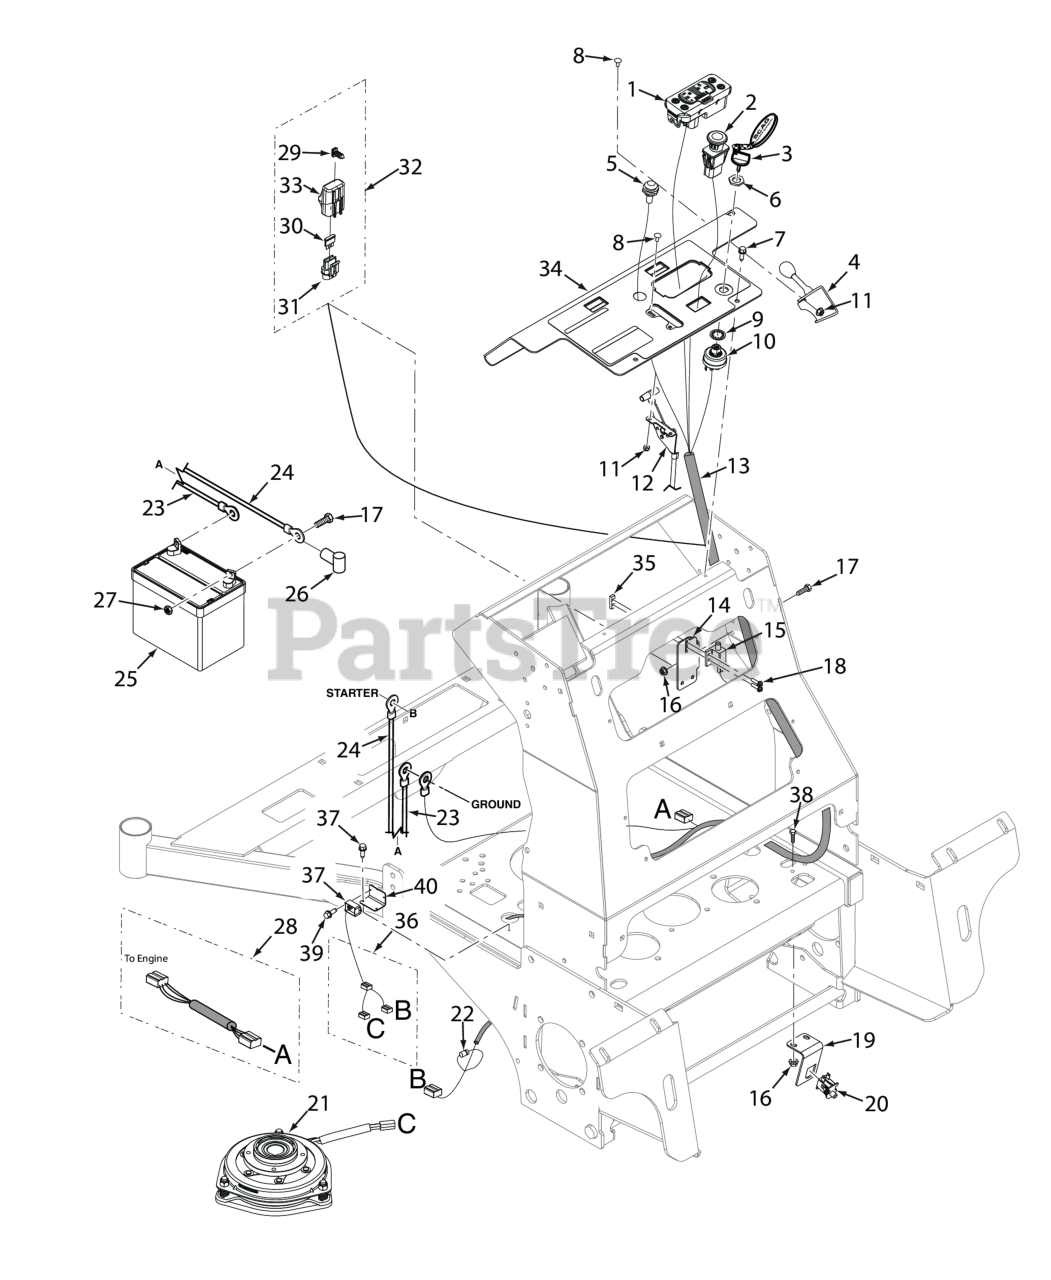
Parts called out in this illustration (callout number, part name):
1	Tiger Eye, Cluster Gauge
2	Switch, PTO - 10 Amp
3	Key, Assembly w/Fob
4	Control Cable, Air Direction
5	Indicator Light, Glow Plugs (Includes Mounting Hardware)
6	Nut, 5/8-32 Special
7	Screw, Self-Tapping 1/4-20 x 3/4
8	Bolt, Carriage #10-24 x 1/2"
9	LOCK WASHER, 5/8" INTERNAL TOOTH
10	KEY SWITCH(INCLUDES MOUNTING HARDWARE)
11	Nut, Elastic Stop #10-24
12	Throttle Control, SVR
13	Wire Harness, SVRII-EFI
14	Bracket, Neutral Switch
15	Switch, Interlock, Park Brake Normally Open
16	NUT, 1/4-20 SERRATED FLANGE HEX HEAD
17	BOLT, HEX HEAD, 1/4-20 X 3/4 GR.5
18	Screw, Hex-Slotted Washer Head #10 32 x 3/4"
19	Mounting Bracket, Footplate Switch
20	SWITCH, NEUTRAL INTERLOCK
21	Clutch, GT3.5 (28.6mm Bore)
22	Diode, 600V 6 Amp
23	Battery Cable, 39" Black (26EFI) - Kohler
24	Battery Cable, 44" Red w/Braid (26EFI) - Kohler
25	Battery, 350 CCA (not available through Scag)
26	RUBBER BOOT
27	Nut, 1/4 - 20 Hex
28	Wire Harness Adapter, Briggs & Stratton 37 BV-EFI
29	Clip, Fuse Holder
30	FUSE, 20 AMP BLADE TYPE AUTOMOTIVE
31	Fuse Holder Assembly
32	Single Fuse Assy., Excluding Fuse
33	Cover, Sealed Single
34	Control Panel w/Decals
35	Plate, Threaded
36	Wire Harness, Clutch Soft Start
37	Soft Start Module, Clutch
38	Serr. Fl. Hex Head CPSCR, 1/4-20 x 3/4"
39	Screw, #10-32 x .563 Shakeproof
40	Mounting Bracket, Soft Start Module
